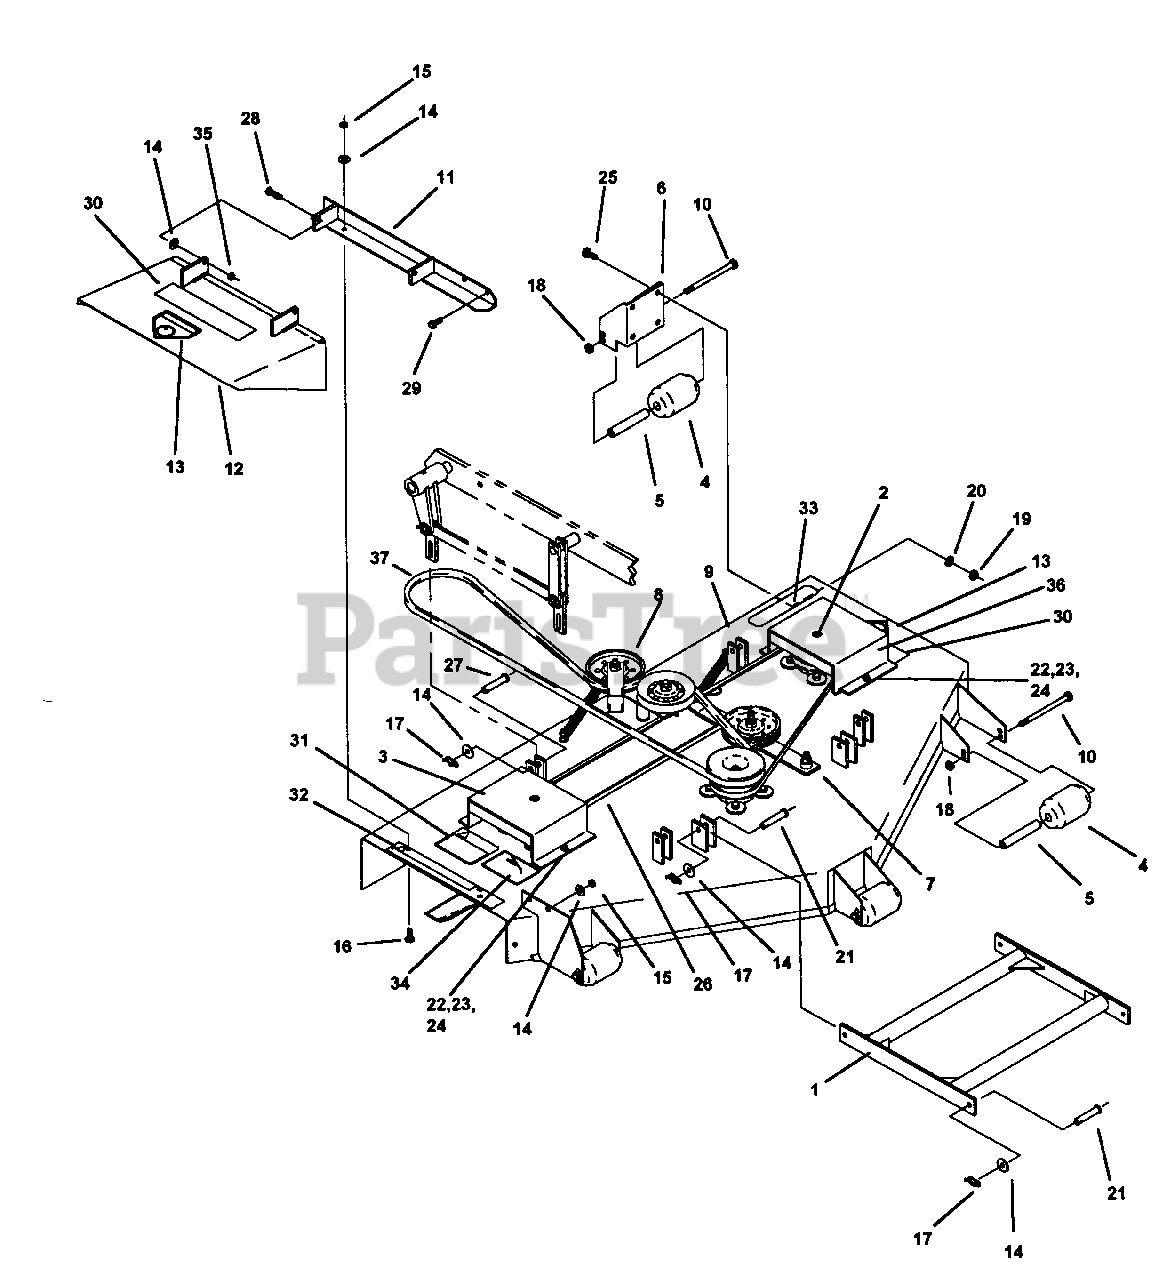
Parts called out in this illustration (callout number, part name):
1	DRAG BAR WELDMENT
2	SPINDLE ASSEMBLY
3	PULLEY COVER, R.H. 48 DECK
4	ROLLER, DECK, BLACK
5	ROLLER SPACER BUSHING
7	SINGLE IDLER PARTS
8	DOUBLE IDLER ASSEMBLY
10	BOLT, 3/8-16 X 4-1/2" GR.5
11	OUTLET STIFFENER WELDMENT, 48" DECK
12	CHUTE WELDMENT (w/decal)
14	WASHER, FLAT STD. 5/16"
15	NUT, 5/16-18 NYLOC
16	BOLT, 5/16-18 X 3/4" CARRIAGE
17	COTTER PIN, SELF LOCKING, 5/16 - 3/8
18	NUT, 3/8-16 TOPLOCK .218 THK.
19	NUT, 3/8-16 NYLOC
20	WASHER, FLAT STD. 3/8"
21	CLEVIS PIN, 5/16 X 1-1/4" LONG
22	BOLT, 1/4-20 X 3/4" GR.5
23	LOCKWASHER, 1/4" SPLIT SPRING
24	WASHER, FLAT STD. 1/4"
25	BOLT, 3/8-16 X 7/8" GR.5
26	DECK CROSS BELT, AP-100
27	CLEVIS PIN, 5/16 X 1-1/2" LONG (4)
28	BOLT, 5/16-18 X 1" GR.5.
29	BOLT, 5/16-18 X 3/4" GR.5
30	DECAL, "MULTI-PERIL"
31	DECAL, "WARNING- ROTATING BLADES"
34	DECAL, "GREASE SPINDLES'
35	LOCKNUT, 5/16-18 STOVER
37	ENGINE TO DECK BELT, BP-81
